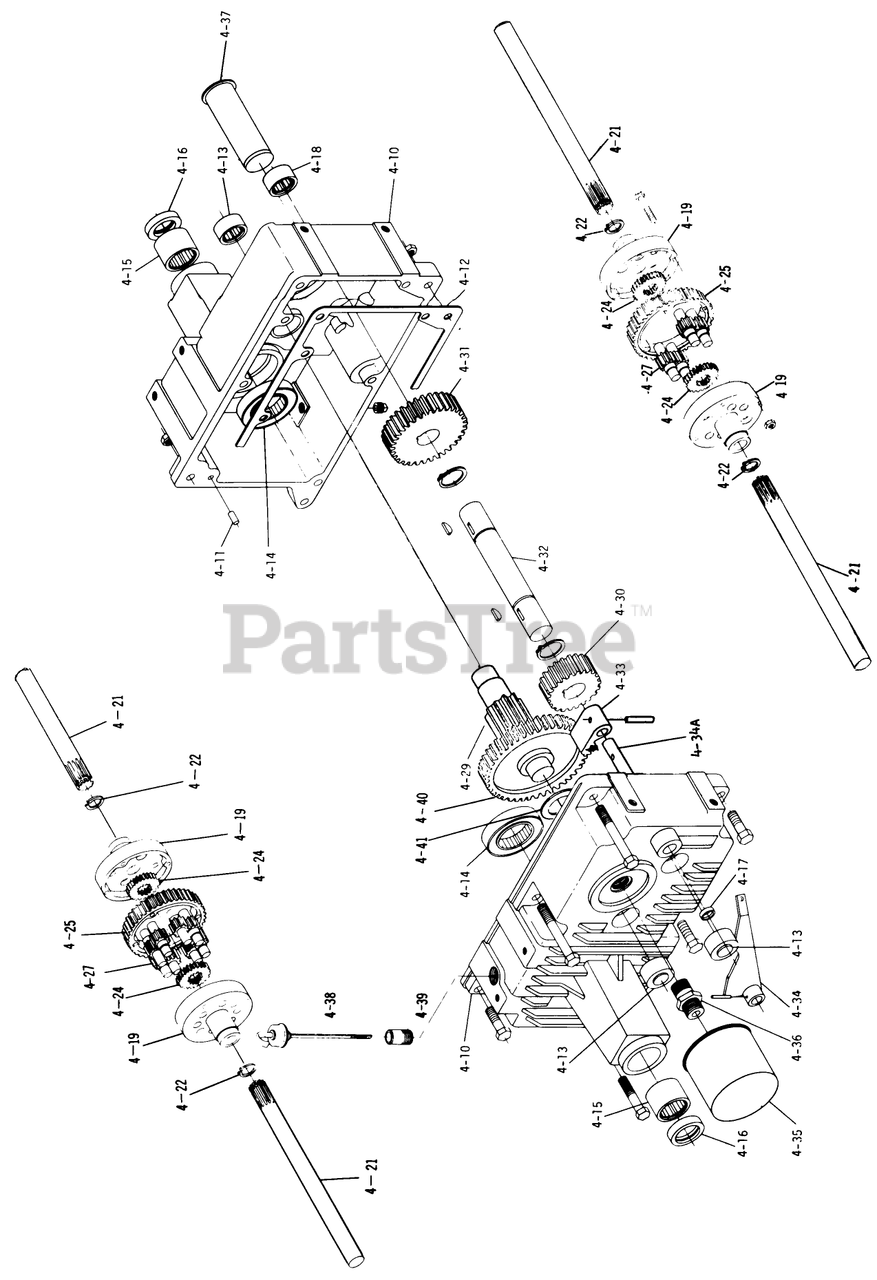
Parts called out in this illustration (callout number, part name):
4-10	Case RH
4-11	PIN-DOWEL
4-13	BEARING-NEEDLE
4-15	BEARING-NEEDLE
4-16	SEAL-OIL
4-19	SVCBULLT 394
4-24	GEAR-AXLE DIFFERENTIAL
4-24	AXLE GEAR
4-25	SVC BULLT 394
4-27	GEAR-PINION, 11T
4-29	PINION SHAFT
4-30	GEAR 24T
4-36	FITTING
4-41	WASHER-THRUST
